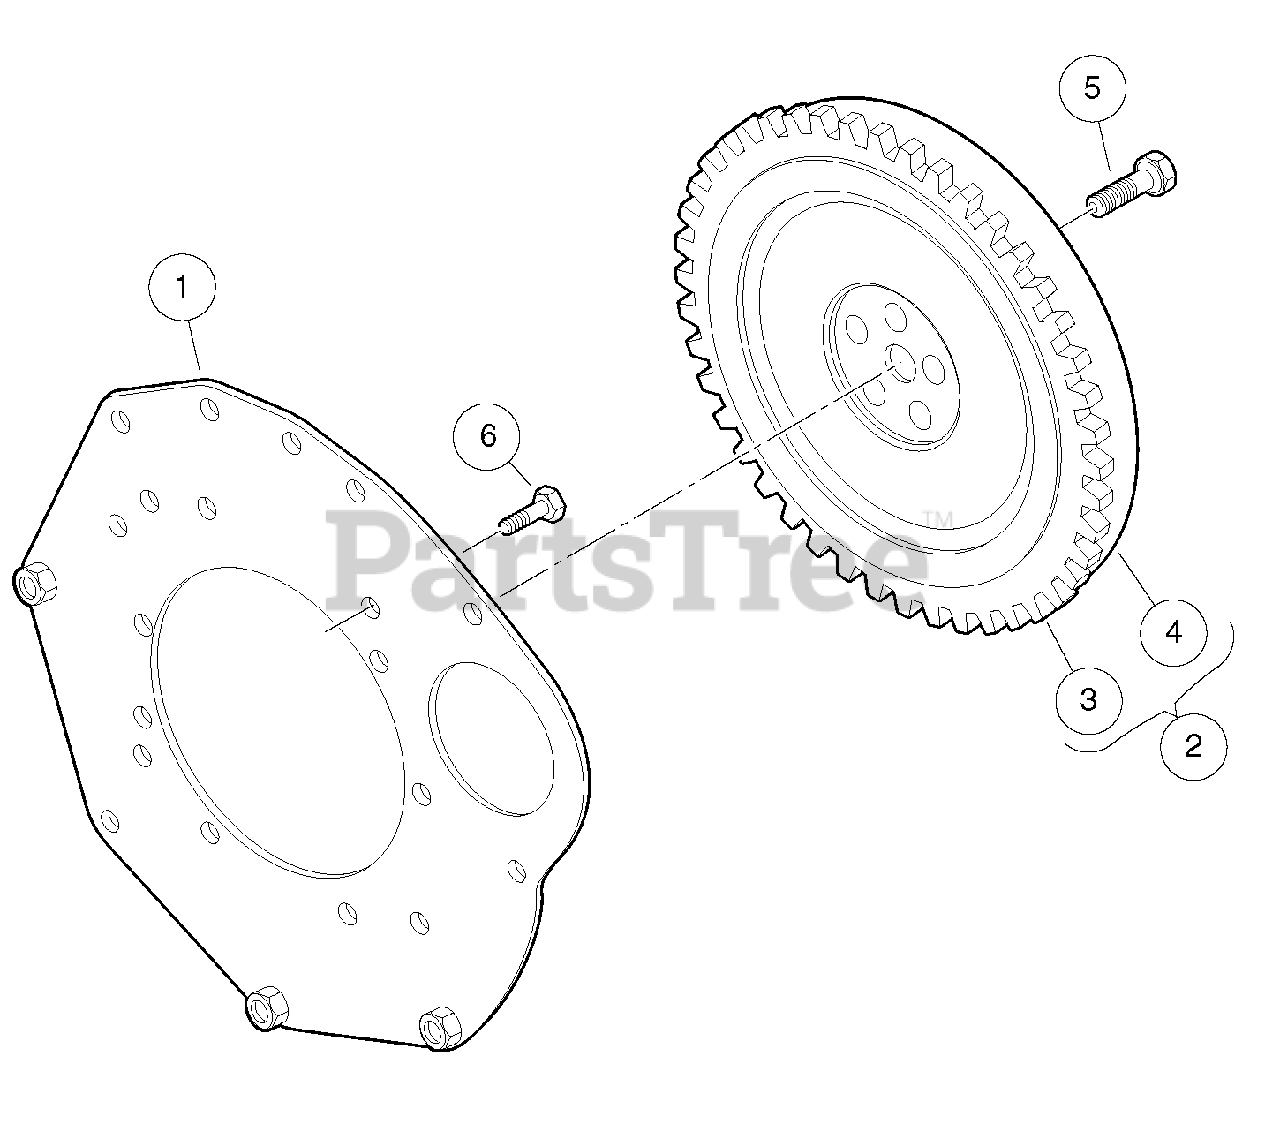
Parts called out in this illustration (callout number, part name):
1	Plate, Rear End
2	Flywheel
3	Gear, Ring, D722
4	Flywheel
5	Bolt, Flange Head, M10 X 1.5 X 25
6	Bolt, End Plate
